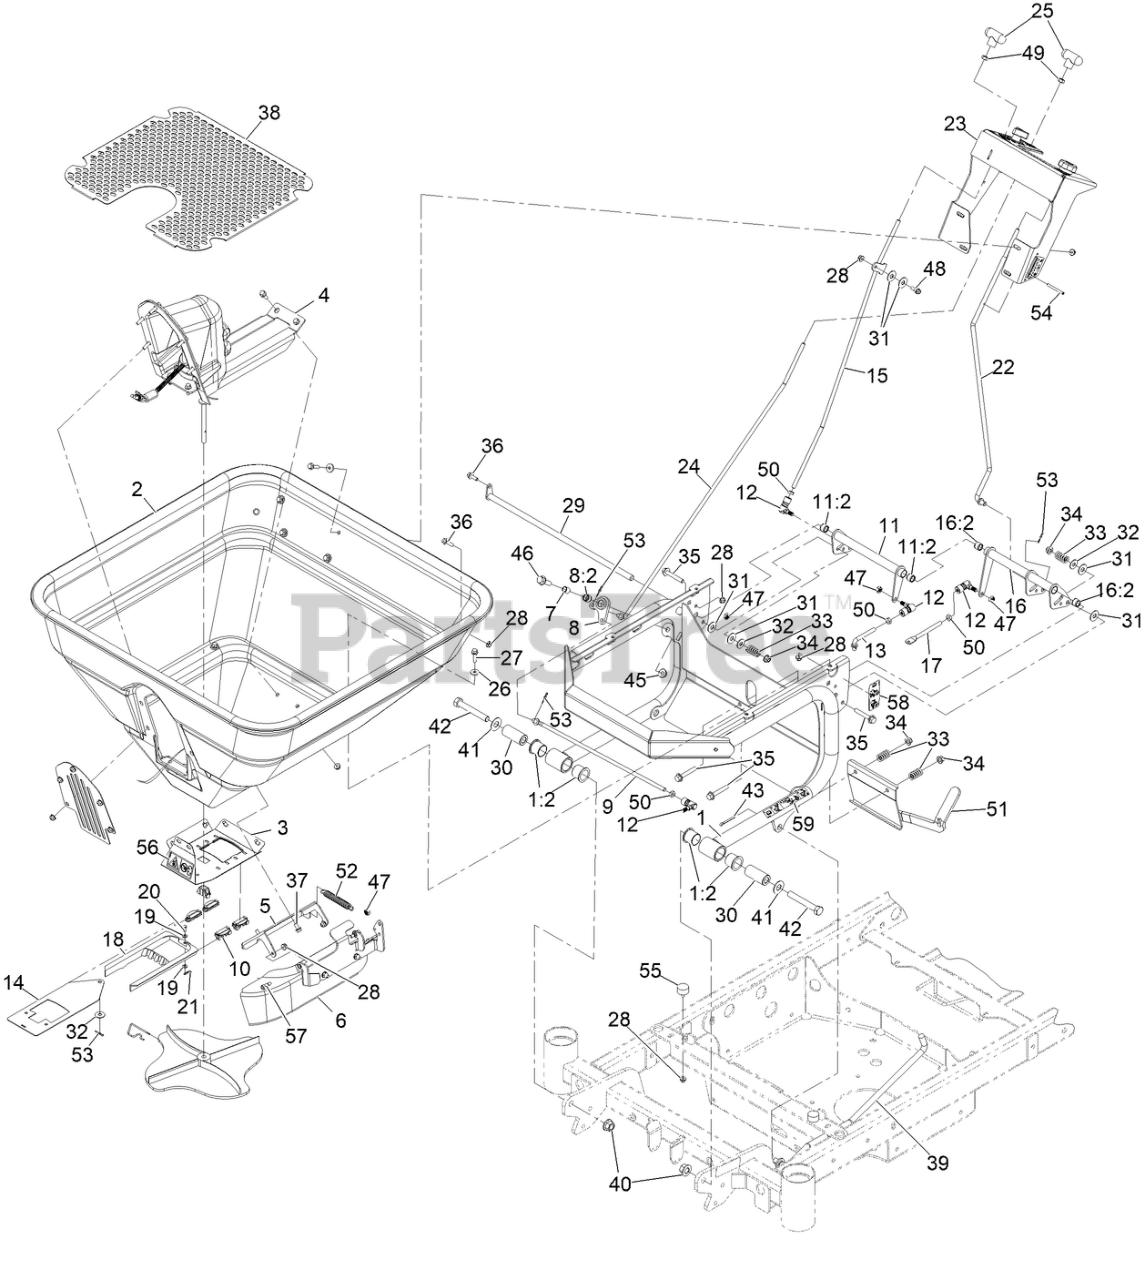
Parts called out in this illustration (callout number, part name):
1	FRAME-HOPPER
1:2	BUSHING-PIVOT
2	HOPPER-250 LB.
3	PLATE-HOPPER, BOTTOM
4	ASM-Motor, Hopper
5	BRACKET-HOPPER DEFLECTOR
6	ASM-Deflector, Side
7	BUSHING-PIVOT, DEFLECTOR
8	CRANK-DEFELCTOR
8:2	BUSHING
9	LINKAGE-DEFLECTOR, LOWER
10	GUIDE-RATE, GATE
11	CRANK-GATE, HOPPER
11:2	BUSHING
12	Ball Joint-Quick Disconnect, SS
13	LINKAGE-GATE, LOWER
14	RATE-GATE
15	LINKAGE-GATE, UPPER
16	CRANK-DIFFUSER
16:2	BUSHING
17	LINKAGE-DIFFUSER, LOWER
18	DIFFUSER
19	WASHER-FLAT
20	PIN-CLEVIS
21	PIN-COTTER, HAIR
22	LINKAGE-DIFFUSER, UPPER
23	ASM-Console, Hopper
24	LINKAGE-DEFLECTOR, UPPER
27	SCREW-HHF
28	Nut-Hex Flange
29	SHAFT-CONTROL, HOPPER
30	SPACER-PIVOT, HOPPER
32	FLAT WASHER, 5/16 NOM,ST
33	SPRING-COMPRESSION
34	Nut-Hex Flange
35	SCREW-HHF
36	Screw-HHF
37	SCREW-HWH
38	SCREEN-HOPPER, MEDIUM
39	ROD-PROP, HOPPER
40	NUT-HEX FLANGE
42	SCREW-HH
43	Pin-Cotter
45	Nut-Hex Flange
46	SCREW-HHF
47	NUT-LOCK, NI
48	BOLT-SHOULDER
49	NUT-HEX
50	Nut-Hex
51	LATCH-HOPPER
52	SPRING-EXTENSION
53	COTTER PIN 5/64X3/4 18-8
54	PIN-ROLL, 3/16 X 2.0
55	BUMPER-RUBBER
56	Decal-Dismemberment Hazard
57	BOLT-SHOULDER
58	DECAL-HOPPER ROTATE
59	DECAL-HOPPER LATCH
